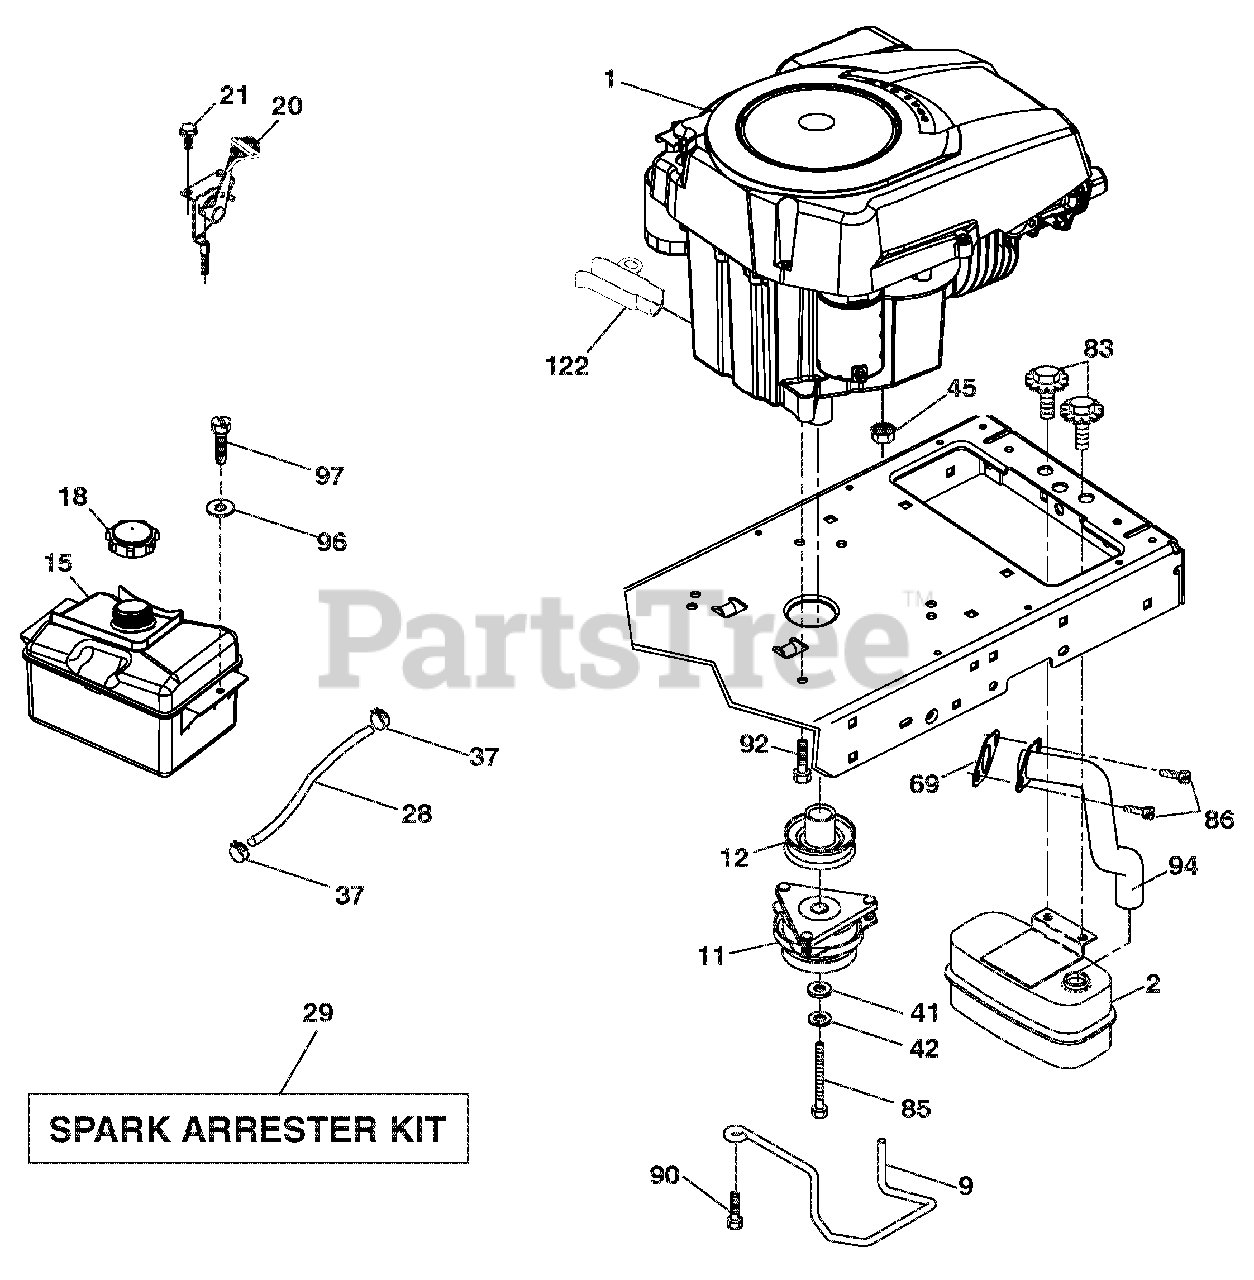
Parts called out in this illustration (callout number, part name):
1	ENGINE KOHL MOD NO. SV590-0218
2	MUFFLER.SINGLE.CYL.KOHL.COURAG
9	KEEPER.BELT.ENGINE.4.25"NSTG
11	CLUTCH OGURA
12	PULLEY.ENGINE.TUFFTORQE.1"CRK.
15	TANK FUEL SIDE FILL 3.00 GA.
18	CAP FUEL
20	CONTROL THROTTLE/CHOKE
28	LINE.FUEL.22"FRONT.EMIS.CA.LP
29	KIT.SPARK ARRESTOR(392390 B&S)
37	CLAMP.HOSE.BLK.
41	WASHER.1-1/2 ODX15/32 IDX.250
42	WASHER.LOCK.HVY HLCL.SPR.7/16
45	Nut, Keps Hex 1/4-20 unc
69	GASKET.KOHLER.SV.I.
83	BOLT.5/16-18UNCX3/4 W/SEMS.BLK
85	BOLT.HEX.7/16-20X4XGR5-1.5THR.
86	SCREW SOCKET HEAD 5/16-18 X 1
90	SCREW.3/8-16X1.SMGML.TAP/R.BLK
92	SCREW.3/8-16 X 1.SMGML.TAP/R
94	TUBE.EXHAUST.KOHL.COURAGE
96	WASHER.9/32 X 7/8 X 16GA.
97	SCREW.HEXWSH.THDROL.1/4-20X3/4
122	Extension Drain Oil
